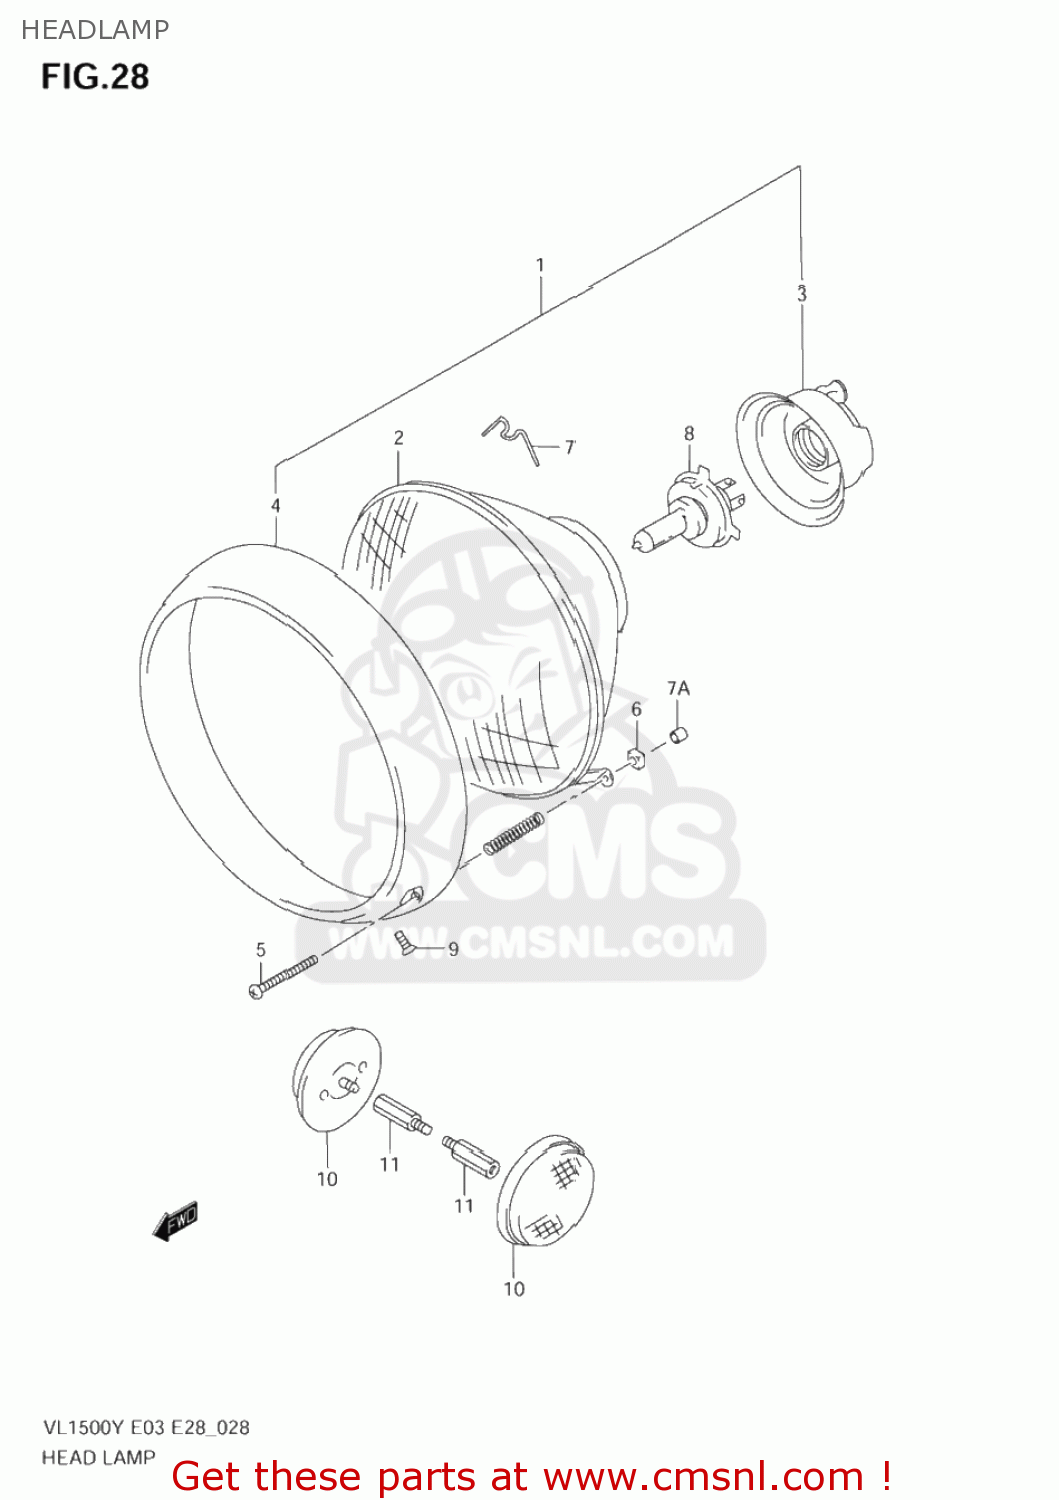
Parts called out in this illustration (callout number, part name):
1	HEADLAMP ASSY
2	LAMP UNIT
2A	RETAINING RING ASSY
3	COVER,SOCKET
4	RIM ASSY
5	SCREW
6	NUT
7	SPRING
7A	CAP,SCREW
8	BULB(12V60/55W,H4)
9	SCREW(5X12)
10	REFLEX REFLECTOR,RR
11	BOLT(5X10)
